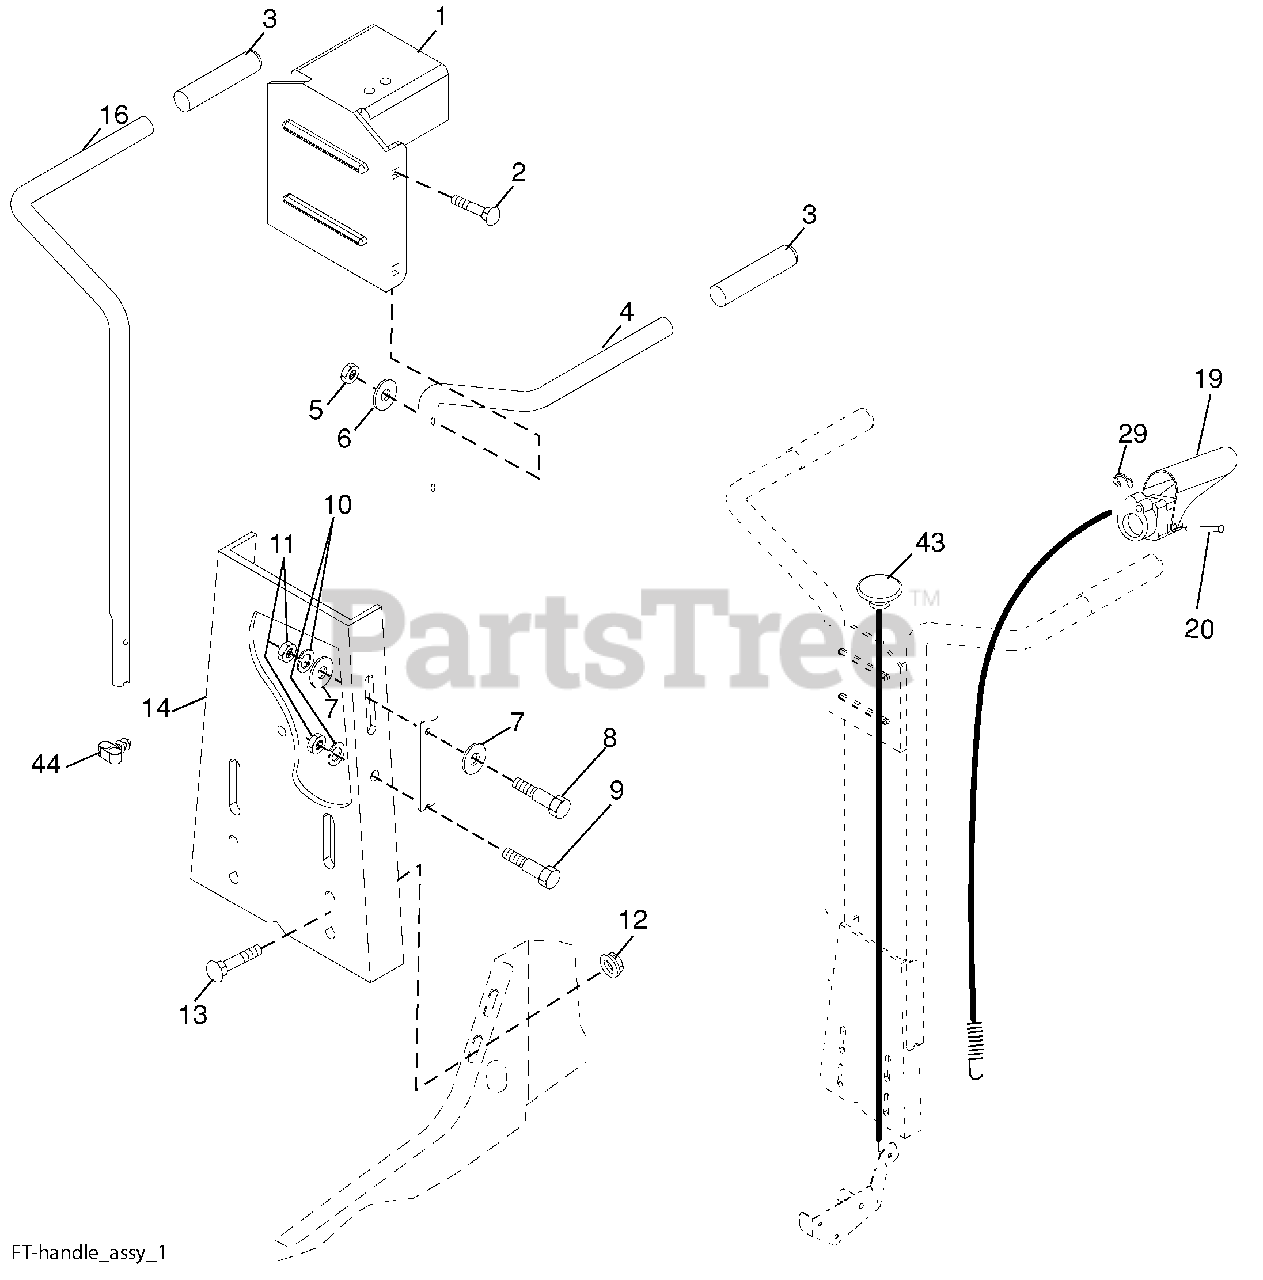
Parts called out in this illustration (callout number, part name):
1	Bracket, Handle
2	Bolt, Carriage 5/16-18 x 1-1/2
3	Grip, Handle
4	Handle, L.H.
5	Nut, Hex, Crownlock 5/16-18
6	Washer 11/32 x 11/16 x 16 Ga.
7	Washer 3/8 x 7/8 x 14 Ga.
8	Bolt, Hex Head 5/16-18 x 1-1/4
9	Bolt, Hex Head 5/16-18 x 1
10	Washer, Lock 5/16
11	Nut, Hex 5/16-18
12	Nut, Hex, Flanged 5/16-18
13	Bolt, Carriage, Gr. 5 5/16-18 x 3/4
14	Panel, Handle
16	Handle, R.H.
19	Tine Control Lever Assembly
20	Pin, Pivot
29	Retaining Ring
43	Cable Assembly, Reverse
44	Clip
